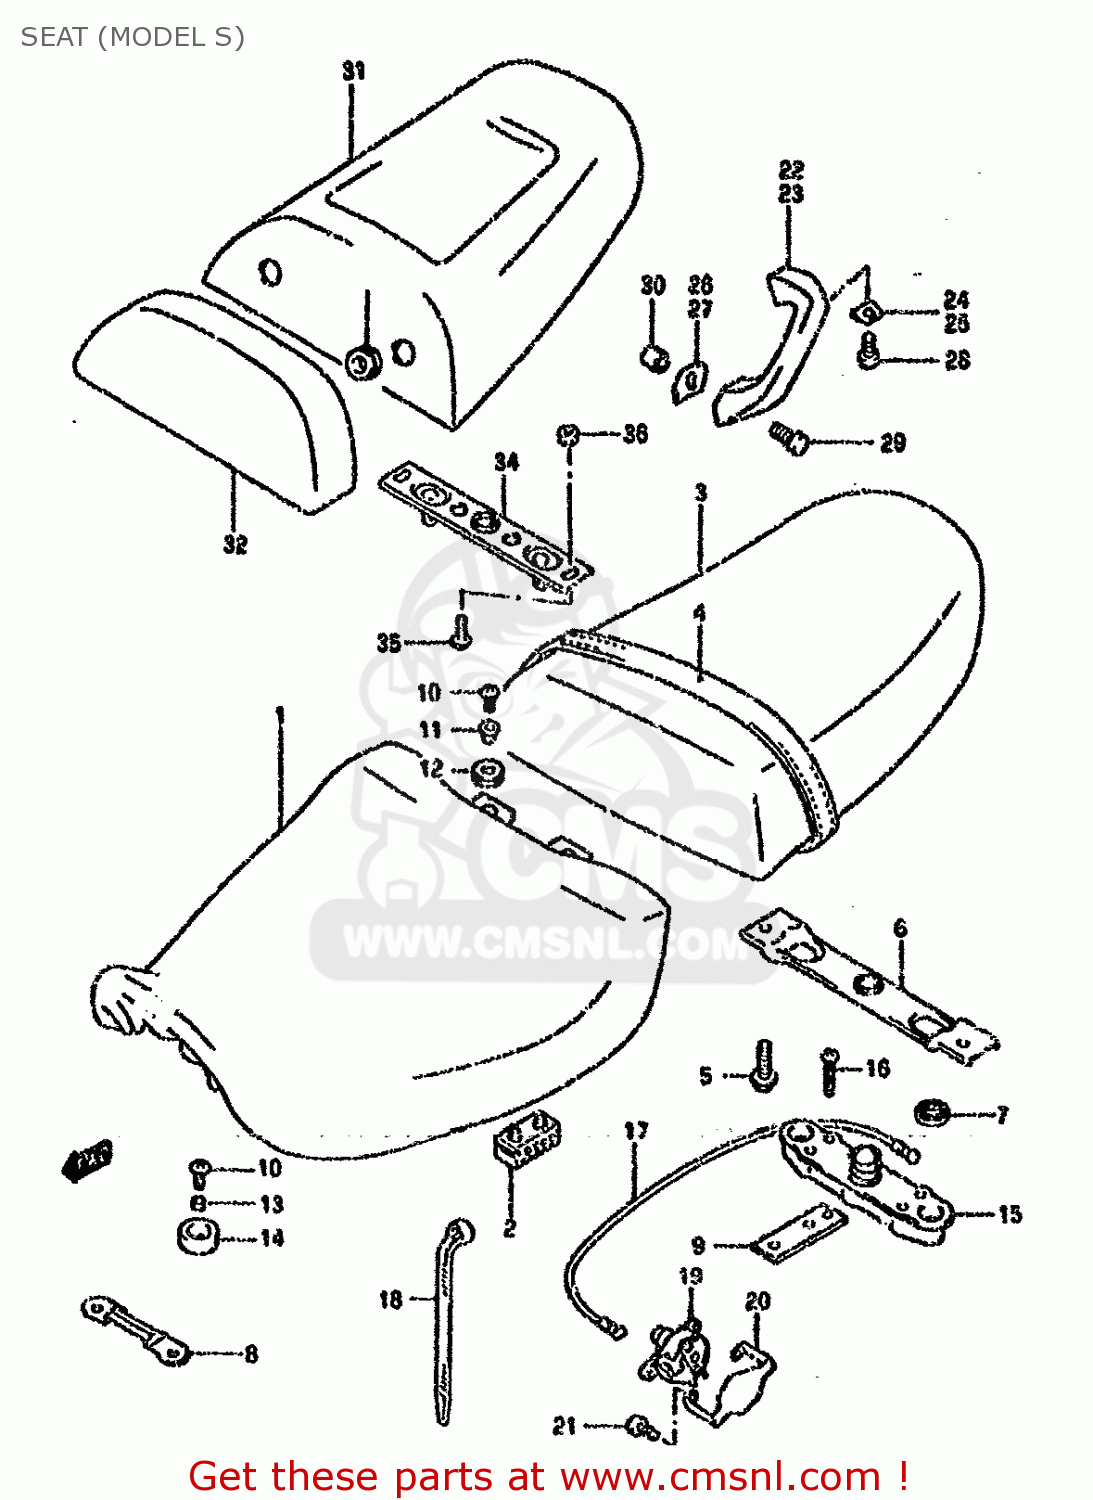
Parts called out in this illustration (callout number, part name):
1	SEAT ASSEMBLY
2	CUSHION,SEAT(40X20X15)
3	SEAT ASSEMBLY,PILLION
4	BAND COMP,SEAT
5	BOLT
6	STRIKER,SEAT LOCK
7	CUSHION
8	PLATE,SEAT FR HOOK
9	BRACKET COMP,SEAT SUPPORT
10	SCREW
11	WASHER
12	CUSHION
13	SPACER (6.8X10X4.7)
14	CUSHION,TAIL COVER UPR
15	LOCK ASSY,SEAT STRIKER
16	SCREW
17	CABLE,SEAT LOCK
18	CLAMP L:165
19	LOCK SET,SEAT
20	PLATE,SEAT LOCK GUARD
21	SCREW(6X12)
22	HANDLE,PILLION RIDER,R
23	HANDLE,PILLION RIDER,L
24	CUSH.,PILLION
25	CUSHION,PILLION HANDLE UPR,L
26	CUSHION,PILLION HANDLE LWR,R
27	CUSH,PILLIONL
28	BOLT
29	BOLT
30	SPACER(8.6X16X20)
31	BOX SET,SEAT TAIL
32	BACKREST COMP,SEAT
33	CUSHION
34	STRIKER,SEAT LOCK
35	SCREW 6X12
36	NUT
